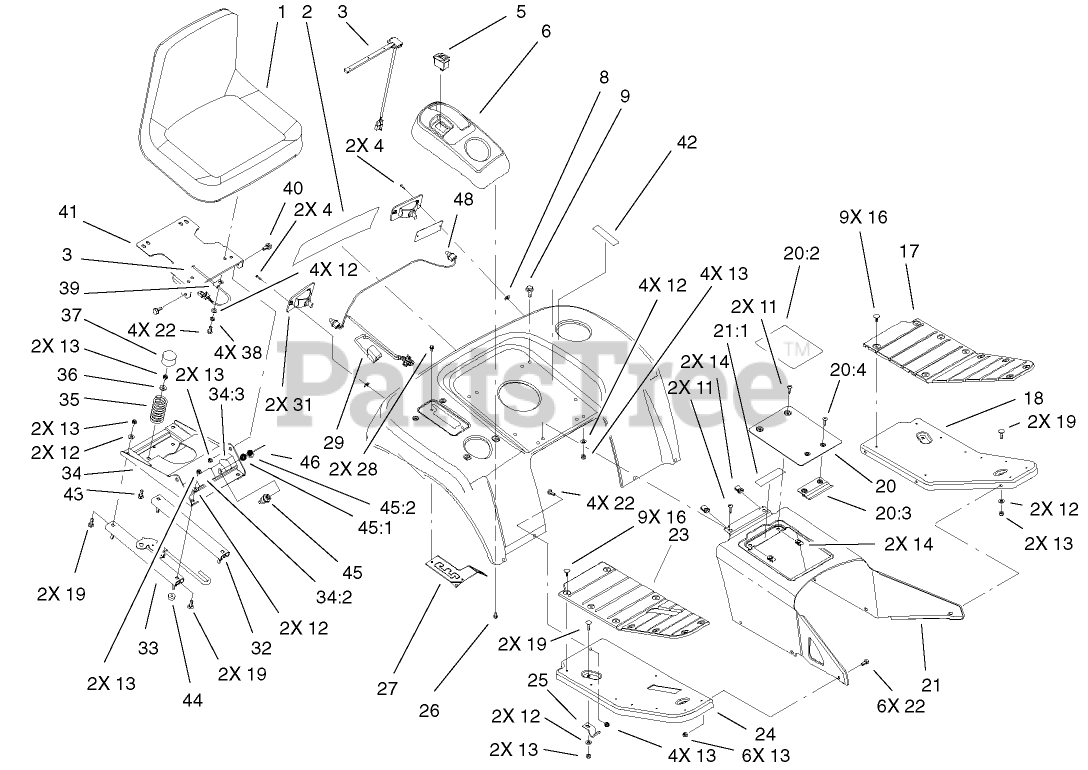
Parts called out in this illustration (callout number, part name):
3	SWITCH-SEAT
4	SCREW-PPH
5	SWITCH-CRUISE
6	POD-CONTROL
6	POD - CONTROL INT'L
8	NUT-SPEED
9	SCREW-HHF
11	SCREW-HH
12	WASHER-PLAIN
13	NUT-LOCK, NI
16	FASTENER-PANEL
17	PAD-FOOTREST, LH
18	FOOTREST-LH
19	SCREW-CARR
20	TUNNEL COVER ASM
20:2	DECAL-DANGER
20:2	DECAL - DANGER
20:3	RETAINER-COVER
20:4	SCREW-PPH
21	TUNNEL ASM
21:1	DECAL - WARNING
21:1	DECAL-DANGER
22	SCREW-HH
24	FOOTREST-RH
25	BRACKET-FOOTREST
26	SCREW-HWH
27	GATE-HI / LO SHIFT
28	SCREW-HWH
29	HARNESS-REAR
31	LAMP-TAILLIGHT
32	SLIDE-SLAVE, SEAT
33	SLIDE-LATCH, SEAT
34	SEAT BASE ASM
34:2	DECAL-DANGER
34:3	DECAL-SWITCH
34:3	DECAL-SWITCH, NMIR
35	SPRING-COMPRESSION
36	BUSHING
37	CAP-SPRING, SEAT
38	WASHER-LOCK
39	CLAMP-R
40	BOLT-SHOULDER,HFH
42	DECAL - DIESEL
43	SCREW-CARR
44	WASHER-FLAT
45	STARTER SWITCH ASM
45:1	WASHER-LOCK
45:2	NUT-HH
46	KEY-IGNITION
48	LIGHT BULB
